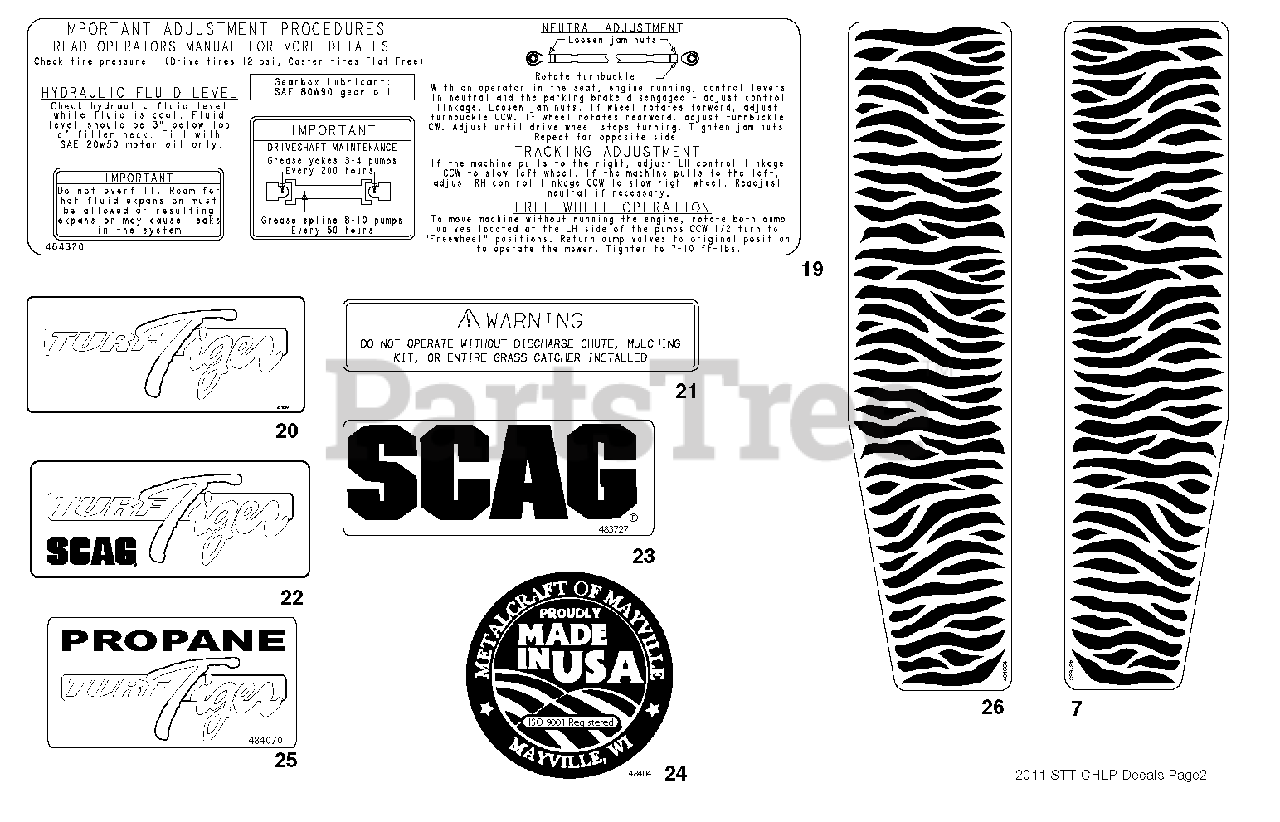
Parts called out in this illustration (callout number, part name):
7	Decal, Stripes-LH
19	Decal, STT Adjustments
20	Decal, Turf Tiger
21	Decal, Warning
22	Decal, Turf Tiger
23	Decal, Scag Logo
24	Decal, Metalcraft-Made In USA
25	Decal, Turf Tiger Propane
26	Decal, Stripes-RH
